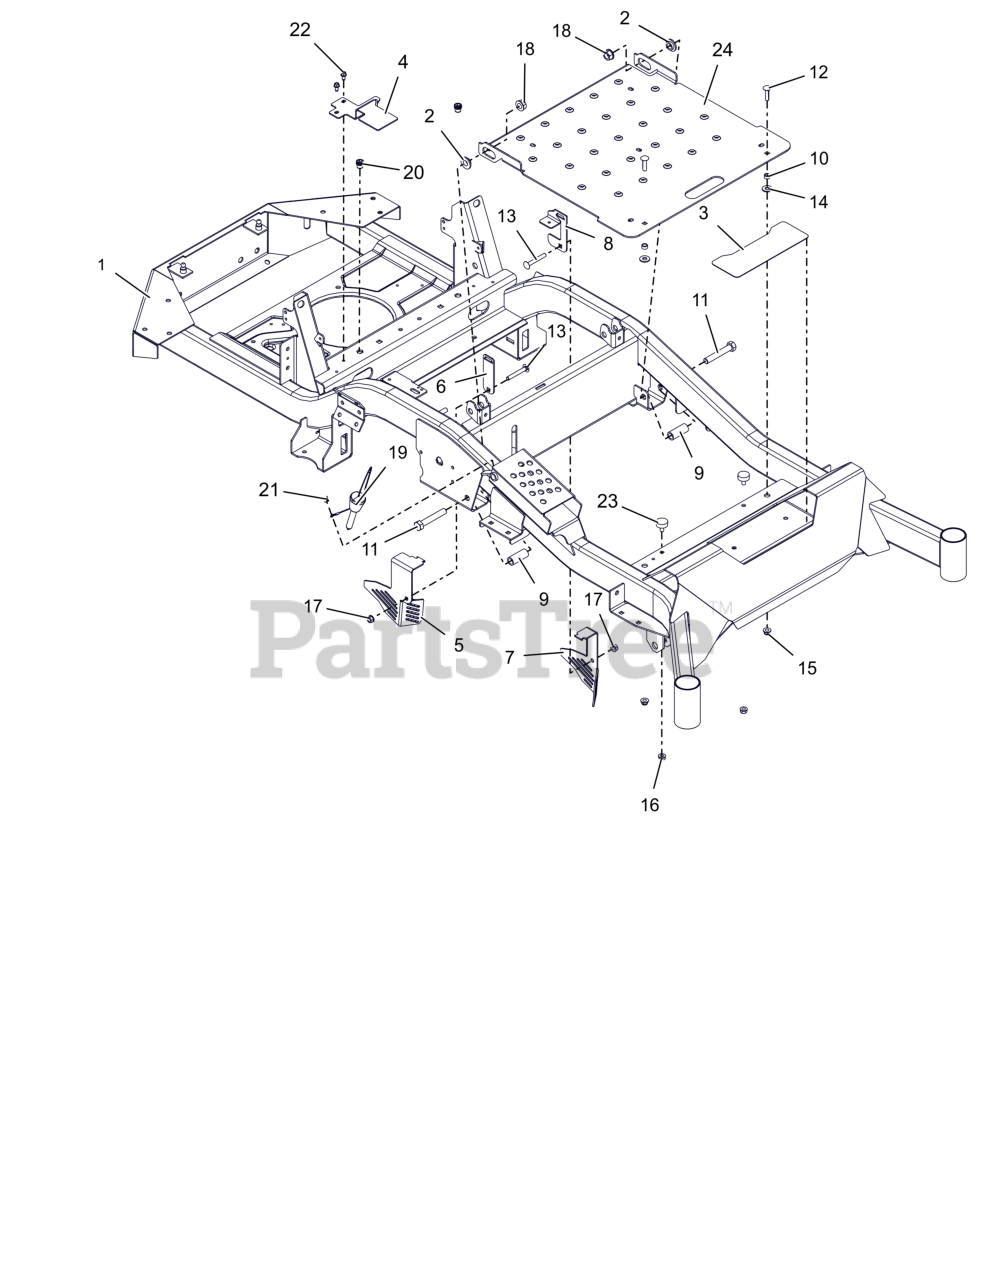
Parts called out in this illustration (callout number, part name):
1	WLDMT, MAIN FRAME -APEX 44-52 (ORANGE)
2	BSHG-FLG .515X.750X.395X1.120
3	GRIP, STEP
4	GUARD, TRANSAXLE FAN RH (BLACK)
5	GUARD, TRANSAXLE FAN - RH
6	BRKT, TRANSAXLE FAN GUARD
7	BRKT, TRANSAXLE FAN GUARD-LH
8	MOUNT, TRANSAXLE GUARD
9	SPACER, .515X.75X1.83
10	BSHG-SLV .344 X .500 X .260
11	BLT, HEX .50-13X3.00 G5 ZCC
12	BLT, RHSSN.31-18X1.25 G5 ZCC
13	BLT, RHSSN.31-18X2.25 G5 ZCC
14	WSHR,FLT .375X.875X.083 ZCC
15	NUT,LK-NYL-FLG .31-18 G5ZC120
16	NUT,SPNLK-FLG .31-18 G5 ZCC
17	NUT,LK-CTR-FLG .31-18 GF ZCC
18	NUT-LK-TOP-FLG .500-13 GF ZCC
19	PIN- MAGNETIC .50X2.70
20	NUT,THD,INSERT .38-16 ZC120
21	POST, & SCREW, PUSH LOCK .25 X .25
22	SCR-TAP .25-20X.50 HWH ZCC
23	BUMPER, RUBBER
24	PANEL, ACCESS
